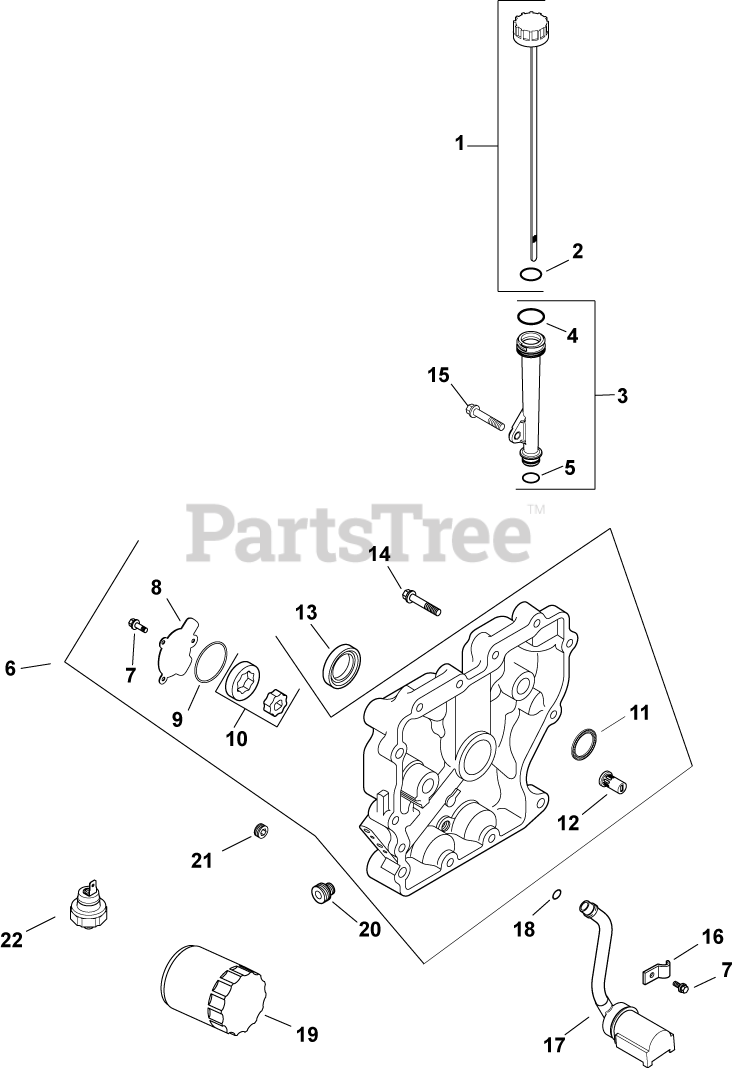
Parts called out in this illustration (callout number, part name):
1	KIT, OIL FILL CAP ASSEMBLY
2	O-RING, UPPER OIL FILL TUBE
3	KIT, OIL FILL TUBE - USE 12 755 113-S
4	O-RING, UPPER OIL FILL TUBE
6	CLOSURE PLATE ASSEMBLY
7	SCREW,FLG THD FRM M5X0.8X16-(#25086398S)
8	COVER, OIL PUMP
9	O-RING (1.78" DIA)
10	PUMP ASSEMBLY, OIL
11	BEARING, CRANKSHAFT
12	VALVE, OIL PRESSURE RELIEF
13	SEAL, OIL
14	SCREW, FLG M8X1.25X45
15	SCREW, FLG M8X1.25X50
17	KIT, OIL PICK-UP
18	O-RING (.5" DIA)
19	FILTER, OIL
20	NIPPLE, OIL FILTER
21	PLUG, CTSK PIPE 1/8"
22	SENSOR, OIL PSI
